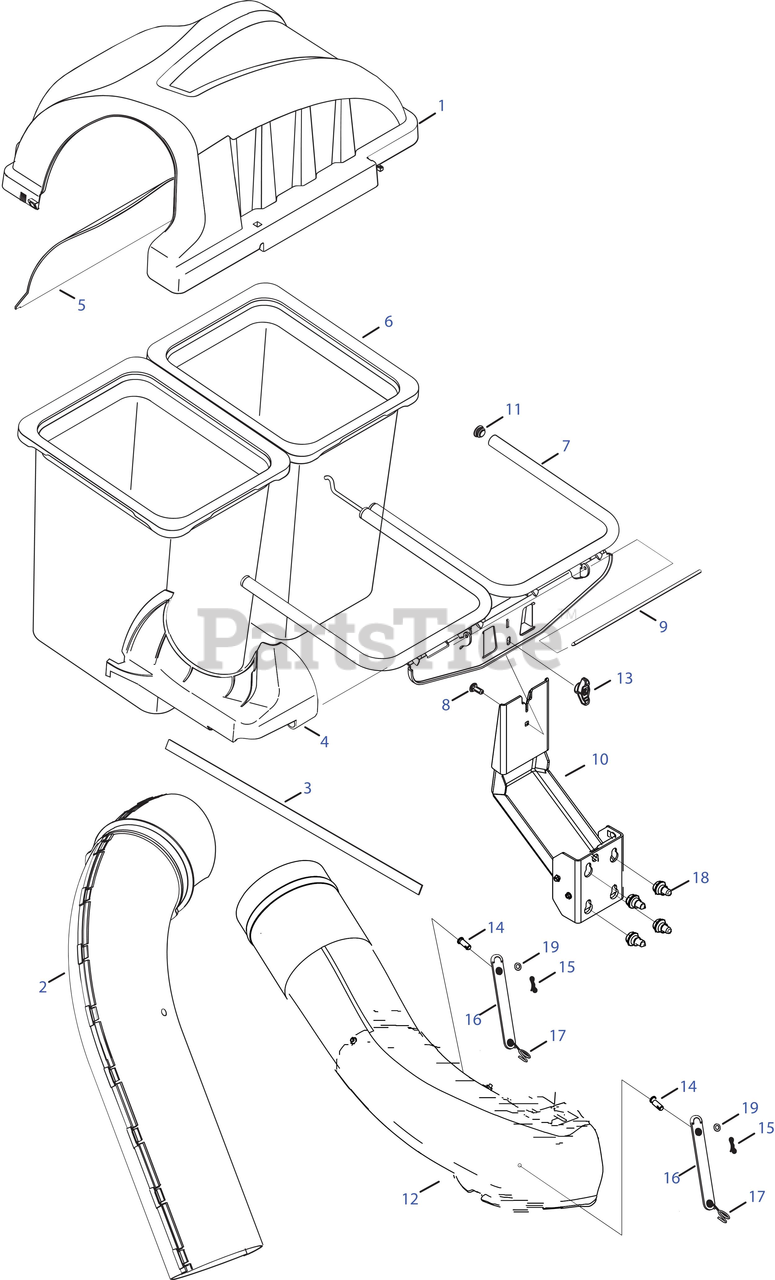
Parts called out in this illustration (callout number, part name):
1	Double Bagger Cover Assembly
2	Upper Chute Assembly
3	Self-Adhesive Foam Strip
4	Upper Chute Support
5	Bagger Cover Screen
6	GrassBag Assembly w/Hard bottom
7	Double Grass-bag Support
8	Carriage Screw, 5/16-18 x 1.00?
9	Cover Hinge Pin
10	Carriage Bolt 1/4-20 x .62
10	Nylon Nut 1/4 x 20
10	Spring Clip
11	End Plug
12	Discharge Chute Elbow
13	Wing Knob, 5/16-18
14	Clevis Pin, 5/16 x .75 Lg.
15	Bow-Tie Cotter Pin, 72
16	Chute Strap, 6.00 Lg.
17	Torsion Spring Hook
18	Shoulder Screw, .43 x .20, 5/16-18
19	Flat Washer, .344 x .620 x .033
